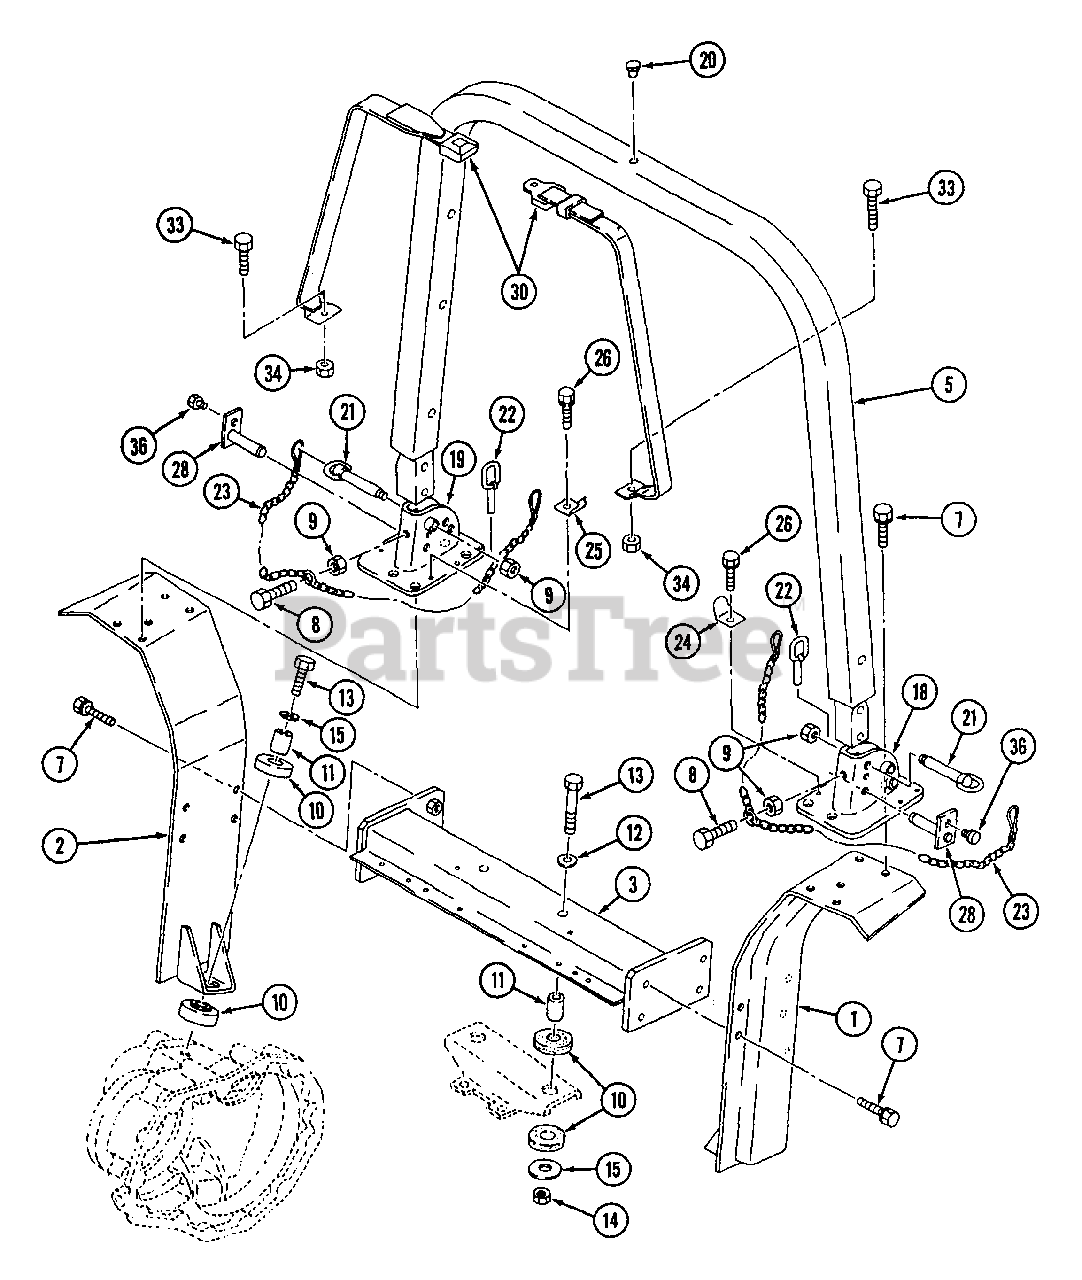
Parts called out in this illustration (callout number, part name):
2	Frame, R.H.
10	Rubber, Cushion
18	Bracket, L.H.
19	Bracket, R.H.
24	Hook, Seat Belt L.H.
25	Hook, Seat Belt R.H.
30	Seat Belt Ass'y.,
